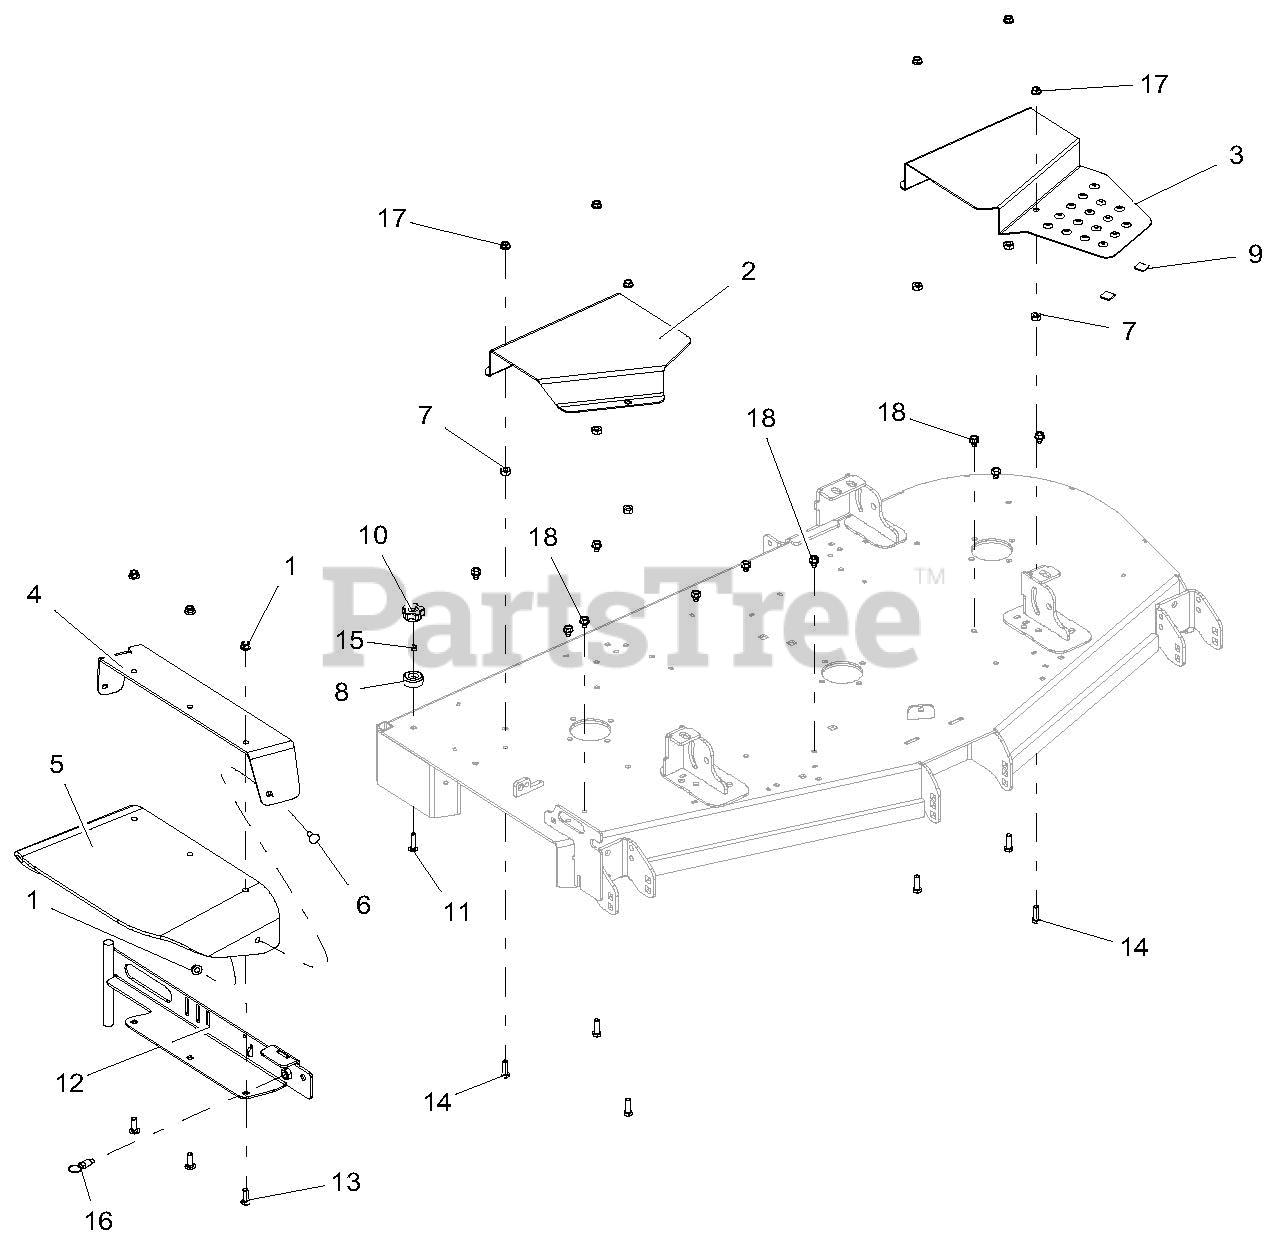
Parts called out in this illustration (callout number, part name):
1	NUT-LK-NYL-FLG .38-16 YWZC
2	GUARD, 60"-66" RH DECK BELT-RED
3	GUARD, 60" LH DECK BELT-W/STEP-RED
4	DISCHARGE CHUTE SUPPORT W/SAFETY DECAL-RED
5	CHUTE, RUBBER DISCHARGE
6	BLT-RDHDSQNK .38-16X1.00 G5 YWZC
7	NUT-HEAVY HEX .38-16 YWZC
8	BUMPER, RECESSED 1.50 X .63 W/.31 HOLE
10	KNOB, CLAMPING
11	BLT-RDHDSQNK .31-18X1.50 G5 YWZC
12	WLDMT, 52"-60" DISCH CHUTE MTG-RED
13	BLT-RDHDSQNK .38-16X1.25 G5 YWZC
14	BLT-HEX .38-16X1.25 GR5 YWZC
15	NUT-LK-CTR .31-18 YWZC
16	PULL PIN,.50-13THDX.310 PLNGR
17	@NUT-SPNLK-FLG .375-16 YWZC
18	SCR-TAP .38-16X.50 HWH TR YWZ
